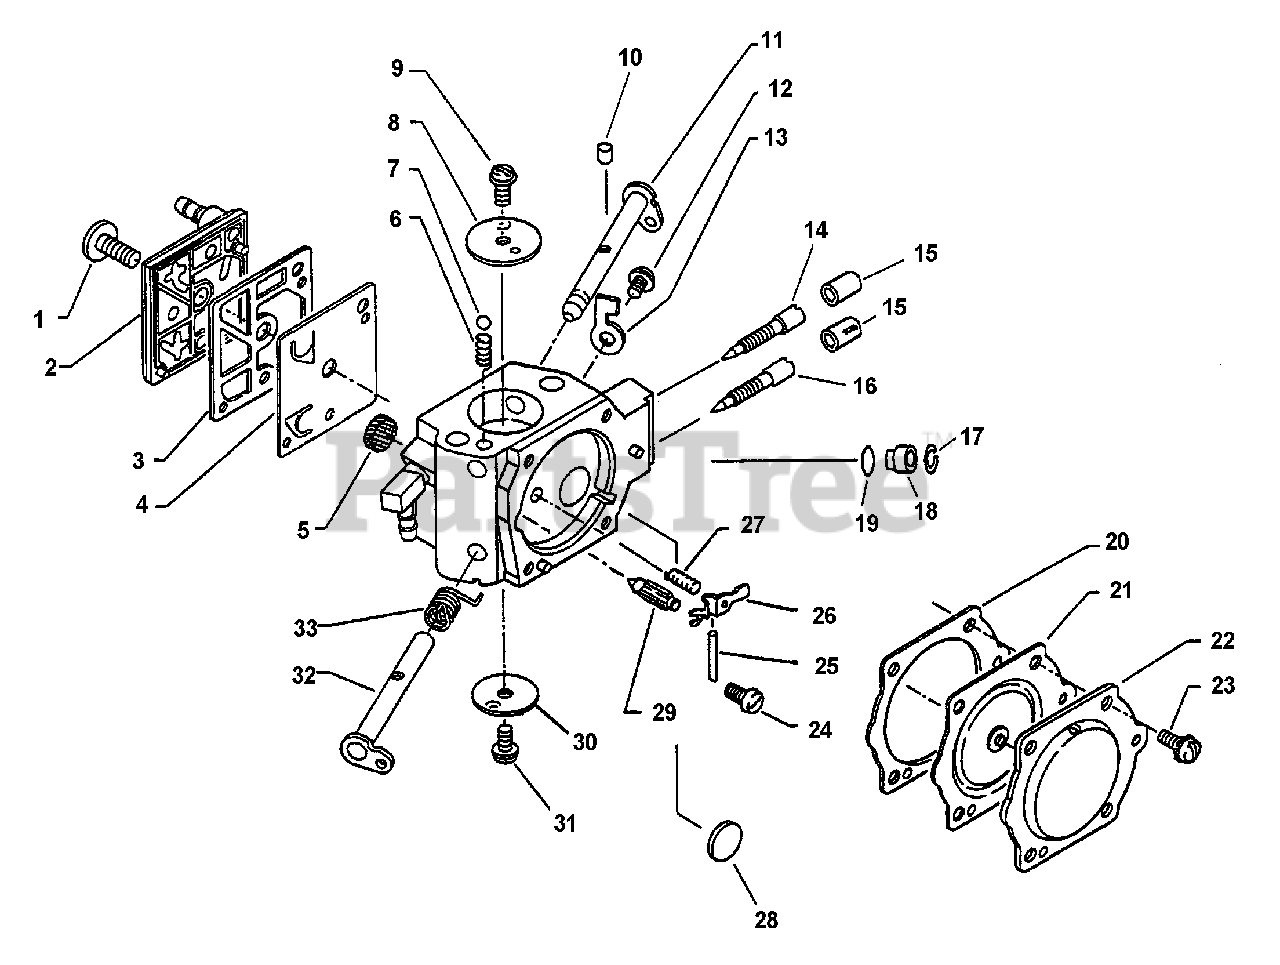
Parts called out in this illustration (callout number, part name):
1	SCREW, PUMP COVER
2	COVER, PUMP
3	GASKET, PUMP
4	DIAPHRAGM, PUMP
5	STRAINER
7	BALL, CHOKE
8	VALVE, CHOKE
11	SHAFT, CHOKE
13	STOP, THROTTLE
14	NEEDLE - HIGH SPEED
15	CAP, LIMITER
16	NEEDLE - MIXTURE
17	RING, RETAINING
18	JET - 42
19	O-RING
20	GASKET, DIAPHRAGM
21	DIAPHRAGM, METERING
22	COVER, METERING
24	SCREW, METERING LEVER PIN
25	PIN, METERING LEVER
26	LEVER, METERING
27	SPRING, METERING LEVER
28	PLUG, WELCH
29	VALVE, INLET NEEDLE
30	VALVE, THROTTLE
32	SHAFT, THROTTLE
33	SPRING, THROTTLE RETURN
